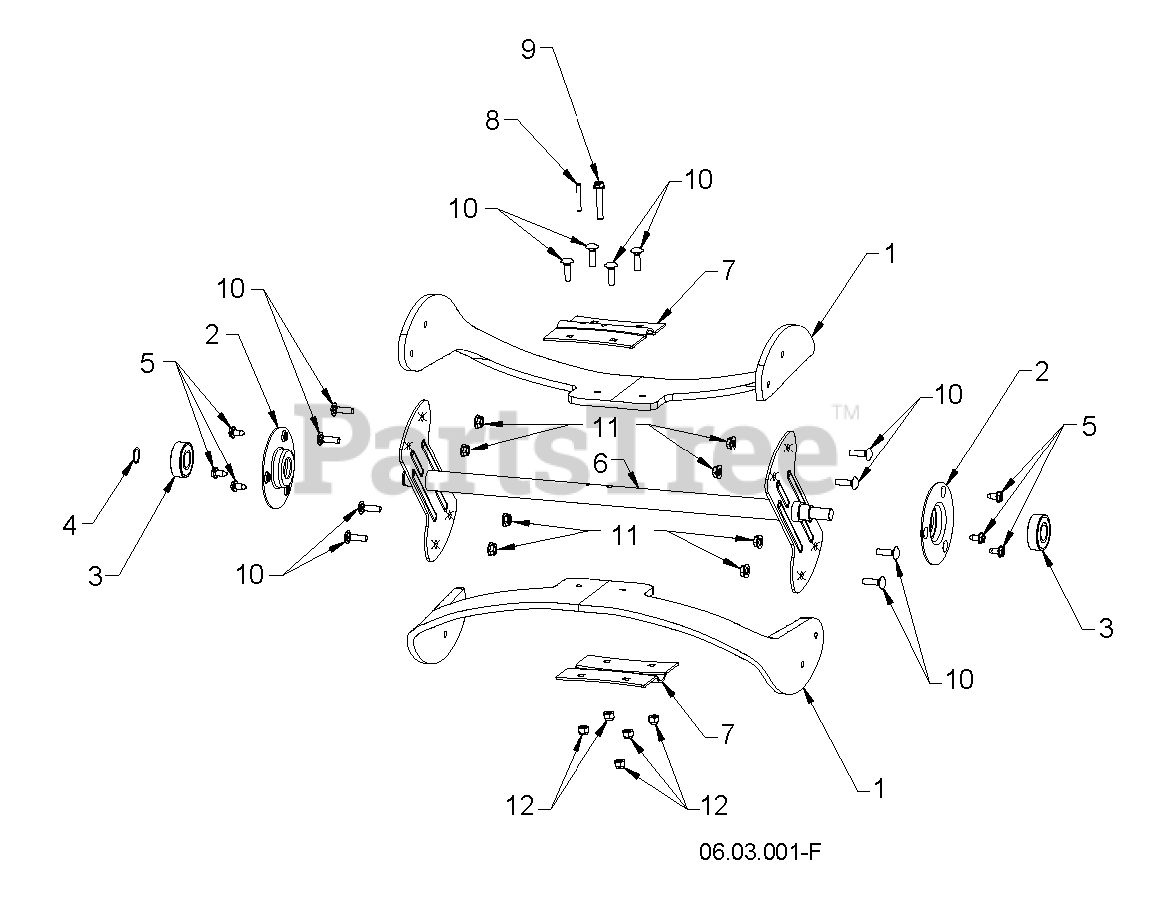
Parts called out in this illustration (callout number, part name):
1	AUGER.BLADE.SS.SNOW
2	SUPPORT.BEARING.SINGLE.STAGE.B
3	BEARING.BALL.MANDREL
4	RETAINING RING LT
6	WELDMENT.AUGER.SINGLE.STAGE.BL
7	PLATE.CENTER.BLADE.BLACK
8	PIN.ROLL.3/16 X 1-1/4
10	BOLT.CARRIAGE.1/4-20 X 7/8
11	NUT.HEX.FLANGE.1/4
12	NUT
